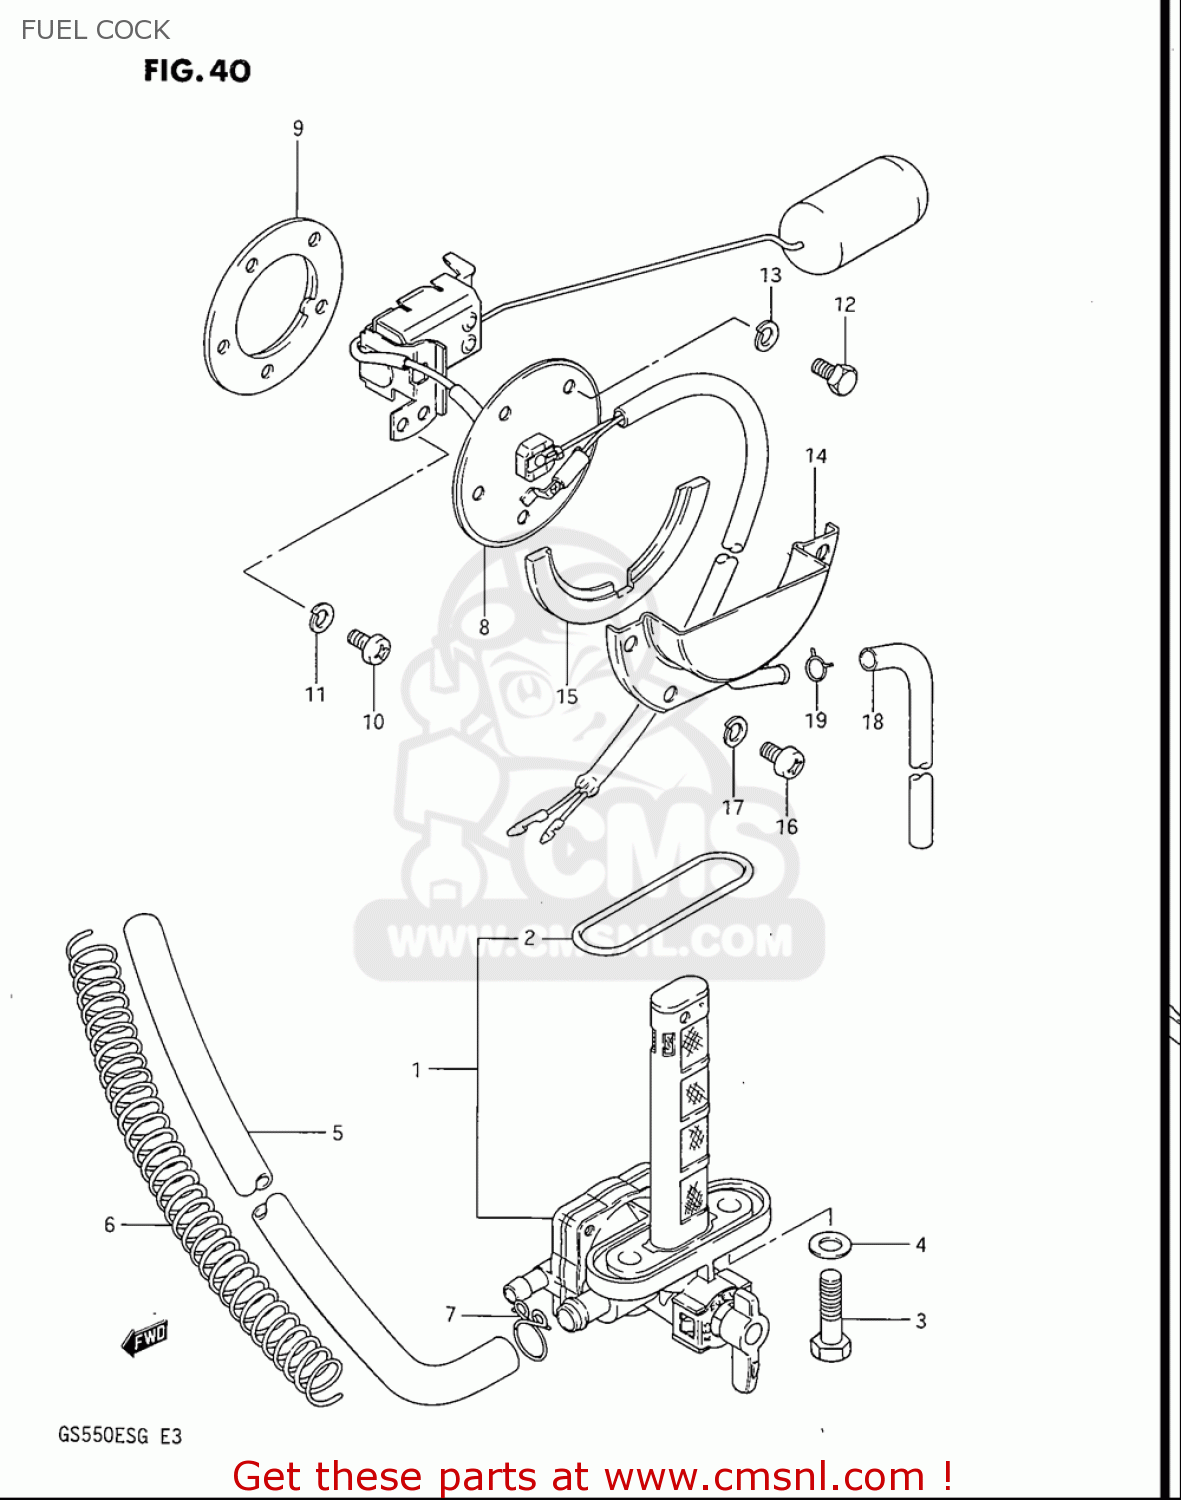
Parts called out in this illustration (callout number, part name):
1	COCK ASSY,FUEL
2	O RING
3	BOLT(6X20)
4	GASKET(5.8X13X1.2) (NAS)
5	HOSE(7X10.2X2000)
6	SPRING
7	CLIP
9	GASKET,FUEL LEVEL GAUGE (NAS)
10	SCREW
11	LOCK,WASHER
12	BOLT
13	LOCK,WASHER
14	PLATE,FUEL DRAIN
15	GASKET (NAS)
16	SCREW
17	LOCK,WASHER
18	HOSE(5X8.2X2000)
19	CLIP
